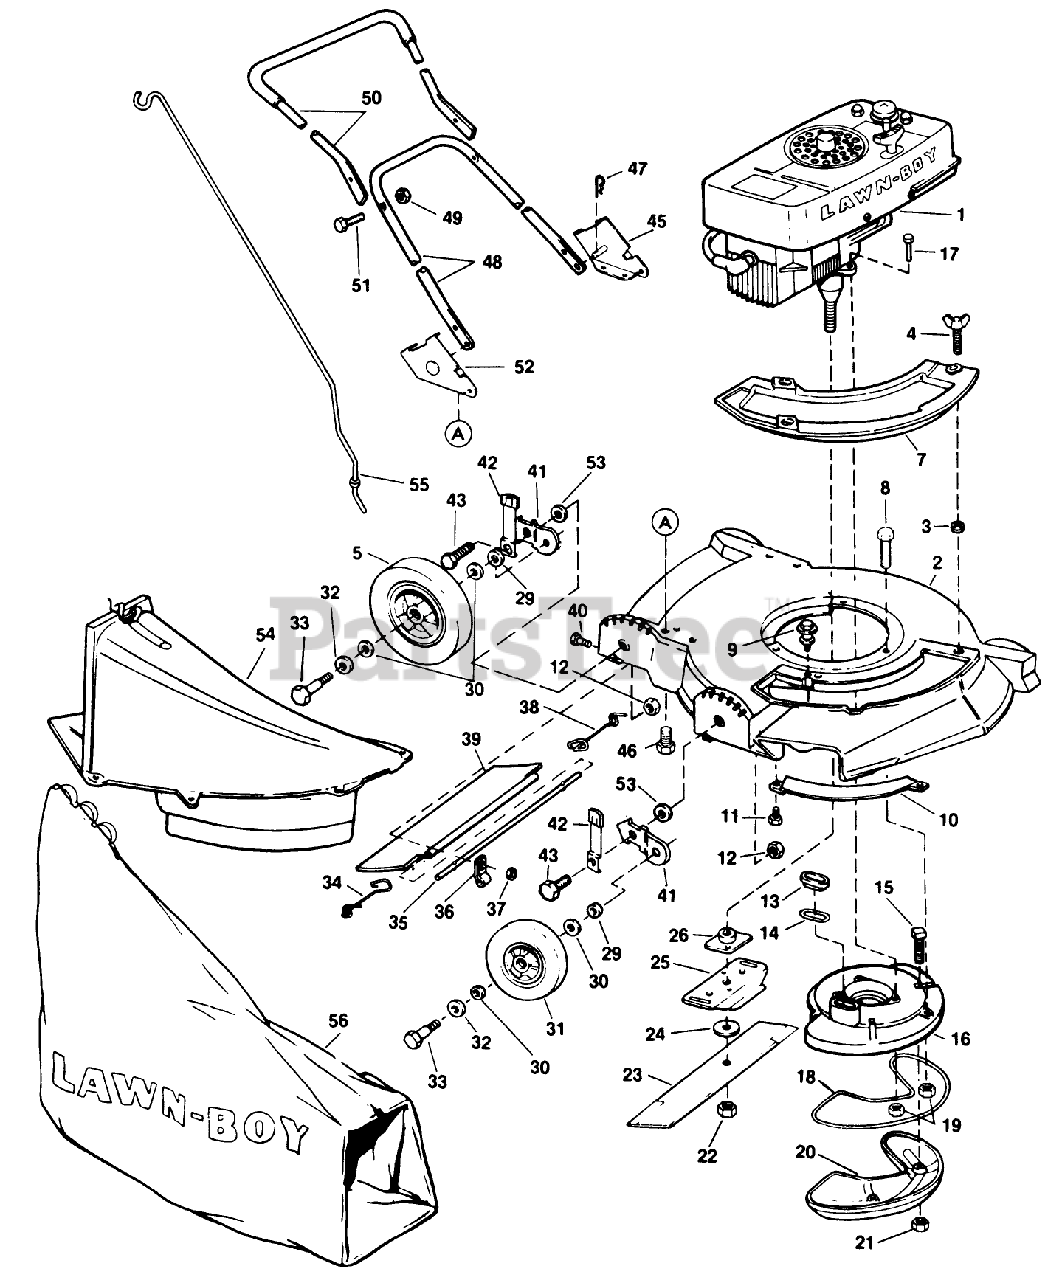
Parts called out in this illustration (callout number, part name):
4	WING SCREW LAWRE
8	SCREW
10	TOE BAR 19"
10	BAR-TOE
12	LOCKNUT
13	SLEEVE
14	GASKET S
15	SCREW
19	NUT-LOCK F
22	NUT-BLADE
24	WASHER
26	PLATE AND COLLAR ASM
29	WASHER WROUGHT
30	WASHER
31	WHEEL & TIRE KIT
32	SPACER
33	BOLT WHEEL
34	SPRING;TRAILING SHIELD RH
35	ROD T/SHIELD ADV WIRE
35	ROD 21" ADVANCE
36	CLAMP ROD KMC
37	LOCKNUT E
38	SPRIG T/SHLD ASOC
46	SCREW
47	HAIR PIN
49	LOCKNUT E
51	SCREW
53	WASHER
55	ROD GRASSBAG
56	89802 LB WHOLE GOODS
